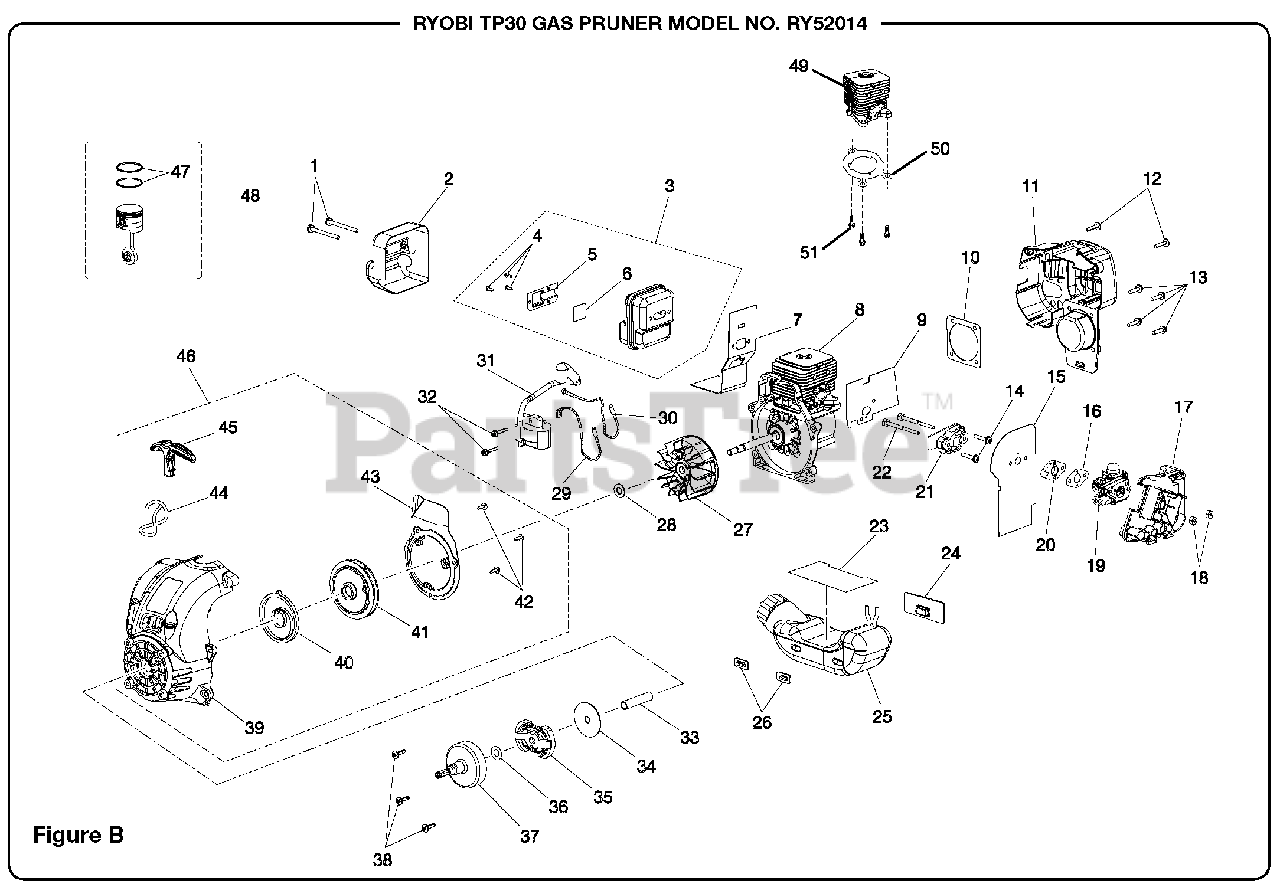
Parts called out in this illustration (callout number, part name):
1	Screw (10-24 X 2-1/8 In. Torx Tr. Hd. )
2	Heat Shield
3	Muffler Assembly
4	Screw (Recessed Pan Hd.)
5	Outlet Tube
6	Screen
7	Muffler Gasket
8	Short Block Assembly (30 Cc) (External Gaskets Not Included)
9	Intake Gasket
10	Cover Gasket
11	Rear Housing
12	Screw (10-14 X 7/8 In. Truss Hd. T.F.)
13	Screw w/Lock Washer(10-24 X 3/4 In. Pan Hd. Torx)
14	Screw (10-24 Pan Hd.)
15	Carburetor Gasket
16	Carburetor Gasket (Non-Strato)
17	Air Filter Base
18	Lock Nut (10-24)
19	Carburetor Assembly
20	Spacer
22	Carburetor Mounting Bolt (10 X 2-1/2 In.)
23	Tank Insulation Gasket
24	Rubber Bumper
25	Fuel Tank Assembly w/Cap
26	Bumper
27	Rotor w/Pawls Assembly
28	Washer
29	Lead w/Terminals
30	Lead w/Terminals
31	Ignition Module w/3 Sec. Kill Switch
32	Screw (8-32 Thd Forming)
33	Spacer Tube
34	Washer (Pkg)
35	Clutch Assembly
36	Clutch Washer
37	Drum And Connector
38	Screw (10-24 X 3/4 In.)
39	Starter Housing And Eyelet Assembly
40	Spring And Container
41	Starter Pulley Assembly
42	Screw (Thread Forming)
43	Baffle/Isolator
44	Starter Rope 42 (Pkg)
45	Starter Grip
46	Starter Housing Assembly
47	Piston Ring
48	Piston w/Rod Assembly
49	Cylinder, 30Cc
50	Cylinder Gasket
51	Screw (M5 X 20 Mm)
